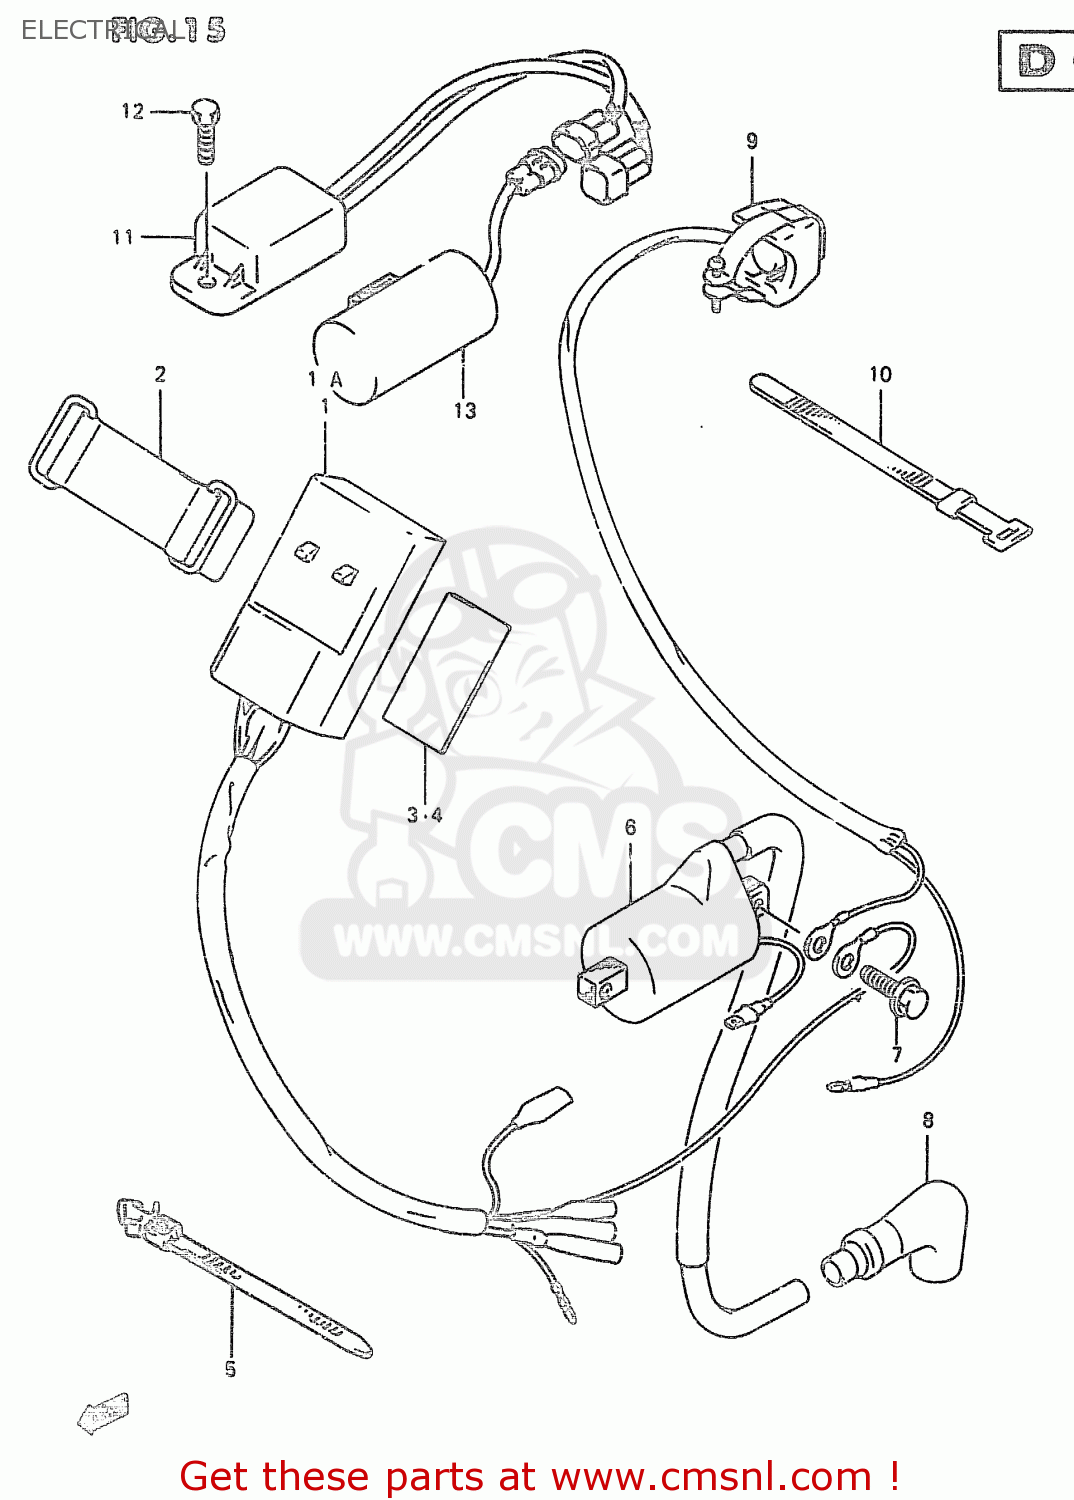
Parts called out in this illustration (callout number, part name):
1	CDI UNIT
1A	CDI UNIT
2	BAND,CDI UNIT(L:80)
3	PROTECTOR(170X95X3.0)
4	PROTECTOR(170X95X3.0)
5	CLAMP(L:90)
6	COIL ASSY,IGNITION
7	SCREW
8	CAP,SPARK PLUG
9	SWITCH ASSY,ENGINE STOP
10	CLAMP(L:120)
11	RECTIFIER ASSY
12	BOLT
13	CONDENSER ASSY
